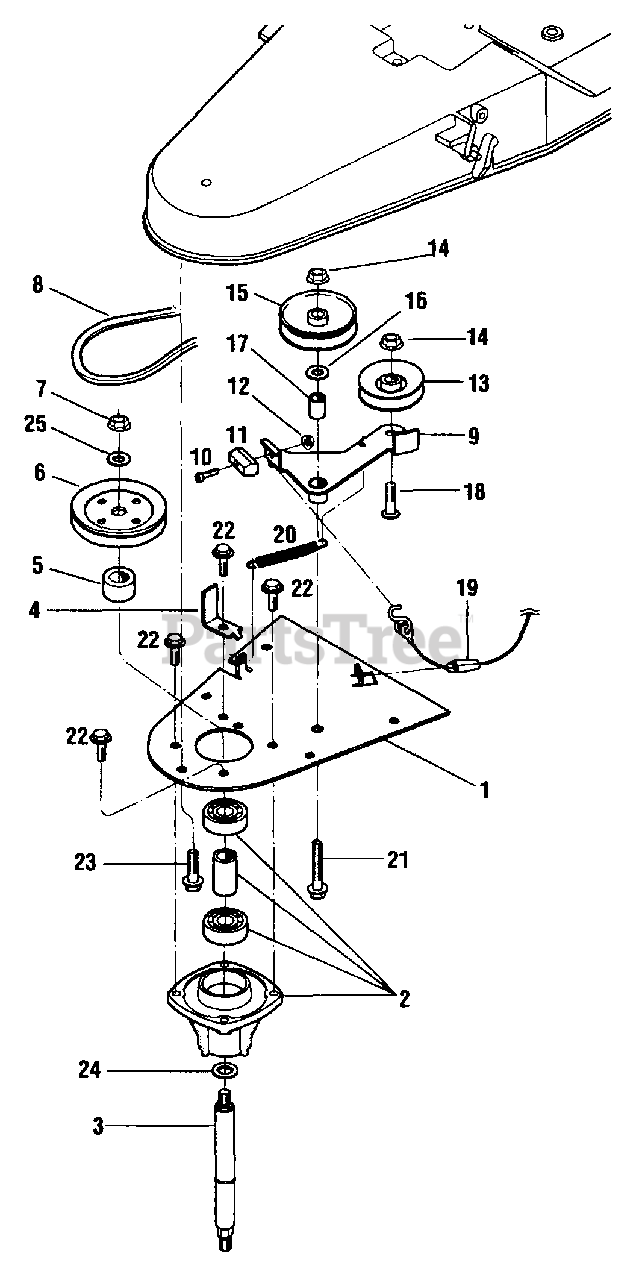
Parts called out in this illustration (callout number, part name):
1	Spindle Mounting Plate
2	Spindle Assembly
3	Spindle Shaft Assembly
4	Belt Guide
5	Spindle Spacer
6	Spindle Pulley
7	Hex Flange Nut, 1/2-13
8	V-Belt
9	Idler Arm/Brake Shoe Assembly
10	Socket Hd Capscrew, 10-24 x 3/4
11	Brake Shoe
12	Hex Lock Nut, 10-24
13	V-Groove Idler Pulley
14	Hex Flange Nut, 3/8-16
15	Flat Idler Pulley
16	Washer, .88 x .382 x .275
17	Idler Arm Spacer
18	Button Head Screw, 3/8-16 x 1-1/2
19	Control Cable
20	Idler Tension Spring
21	Hex Flange Screw , 3/8 x 16 x 2-1/4
22	Hex Flange Screw, 5/16-18 x 3/4
23	Hex Flange Screw, 5/16-18 x 1
24	Hardened Shim, 3/4 ID x 1.022 OD x .060 thick
25	Belleville Washer, 5/8
